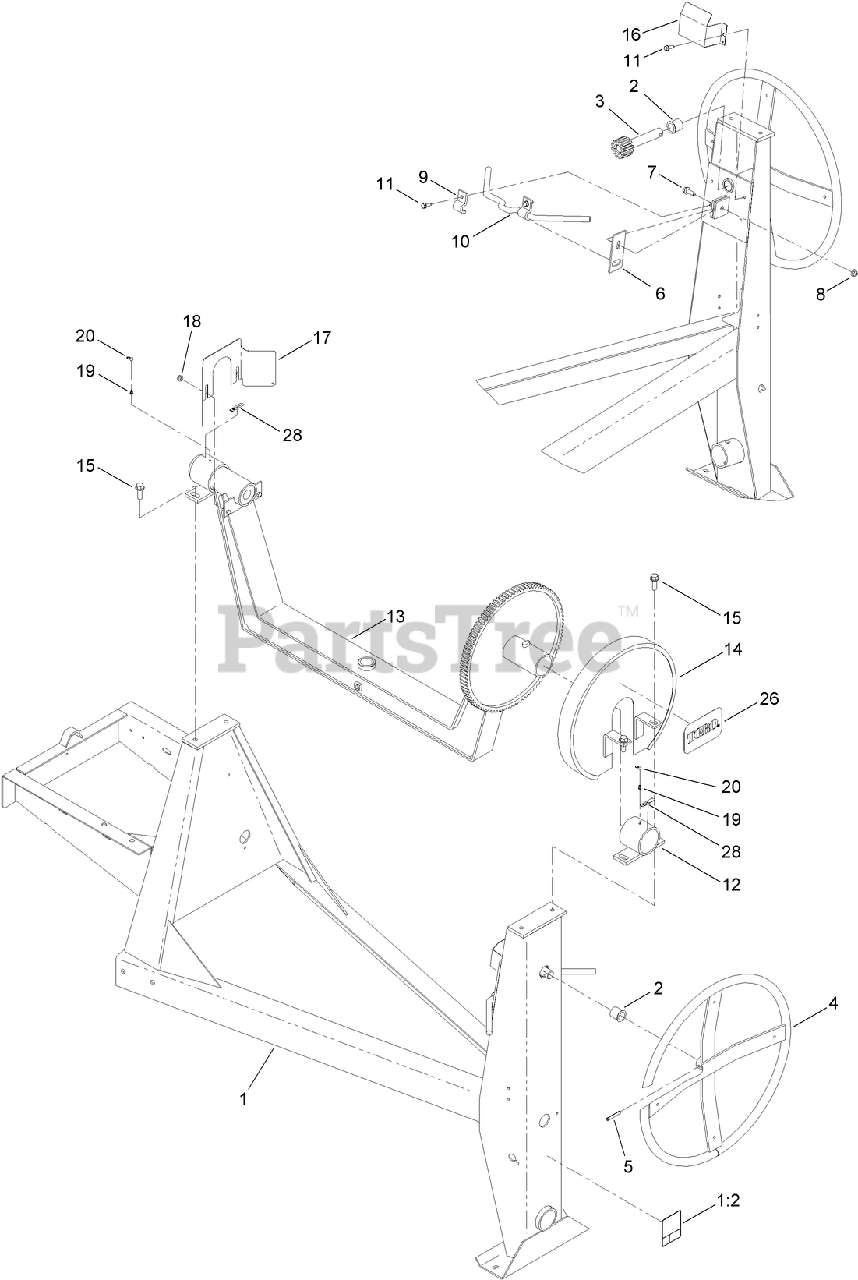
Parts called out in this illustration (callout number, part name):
1	FRAME ASM
1:2	DECAL-SAFETY CHAIN, TOWING
2	BUSHING-NYLON
3	SHAFT-TILT
4	HANDWHEEL
5	PIN-ROLL
6	DOG-BRAKE
7	SCREW-HHF
8	NUT-HF, NI
9	BRACKET-HANDLE
10	HANDLE-BRAKE
11	SCREW-HWHTF
12	TRUNNION
13	YOKE ASM
14	GUARD-BRAKE, UPPER
15	SCREW-HWH
16	GUARD-BRAKE, LOWER
17	GUARD-PINION
18	NUT-HF, NI
19	FITTING-GREASE
20	CAP-PLUG
26	DECAL
28	DECAL-GREASE
